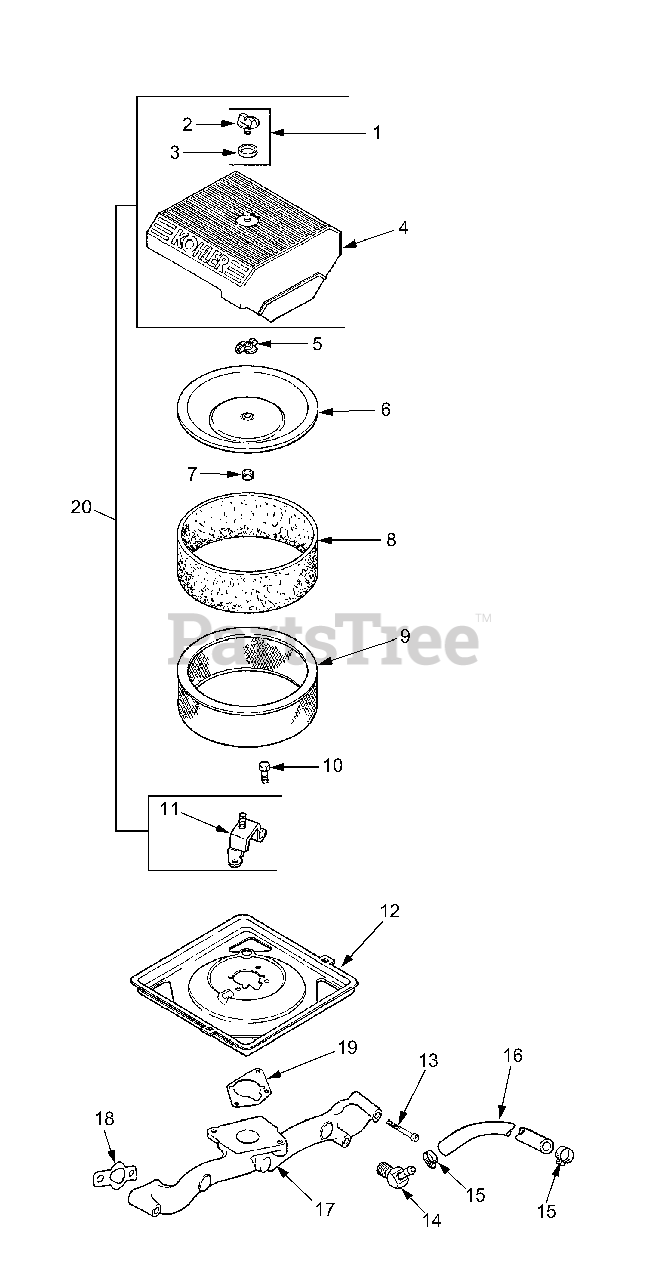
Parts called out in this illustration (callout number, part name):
1	Kit, Knob w/Seal
3	Seal, Air Cleaner Cover Knob
4	Cover, Air Cleaner
6	Cover, Inner Air Cleaner
7	Seal, Inner Air Cleaner
8	Precleaner, Element
9	Element, Air Cleaner
10	Screw, Hex Flange M6 x 1.0 x 16
11	Bracket, Air Cleaner Base
12	Base, Air Cleaner
13	Screw, Hex Flange M6 x 1.0 x 55
14	Connector, Hose 45°.
15	Clamp, Hose
16	Line, Fuel 17"
17	Manifold, Intake
18	Gasket, Intake Manifold
19	Gasket, Air Cleaner Base
20	Kit, Air Cleaner Cover
